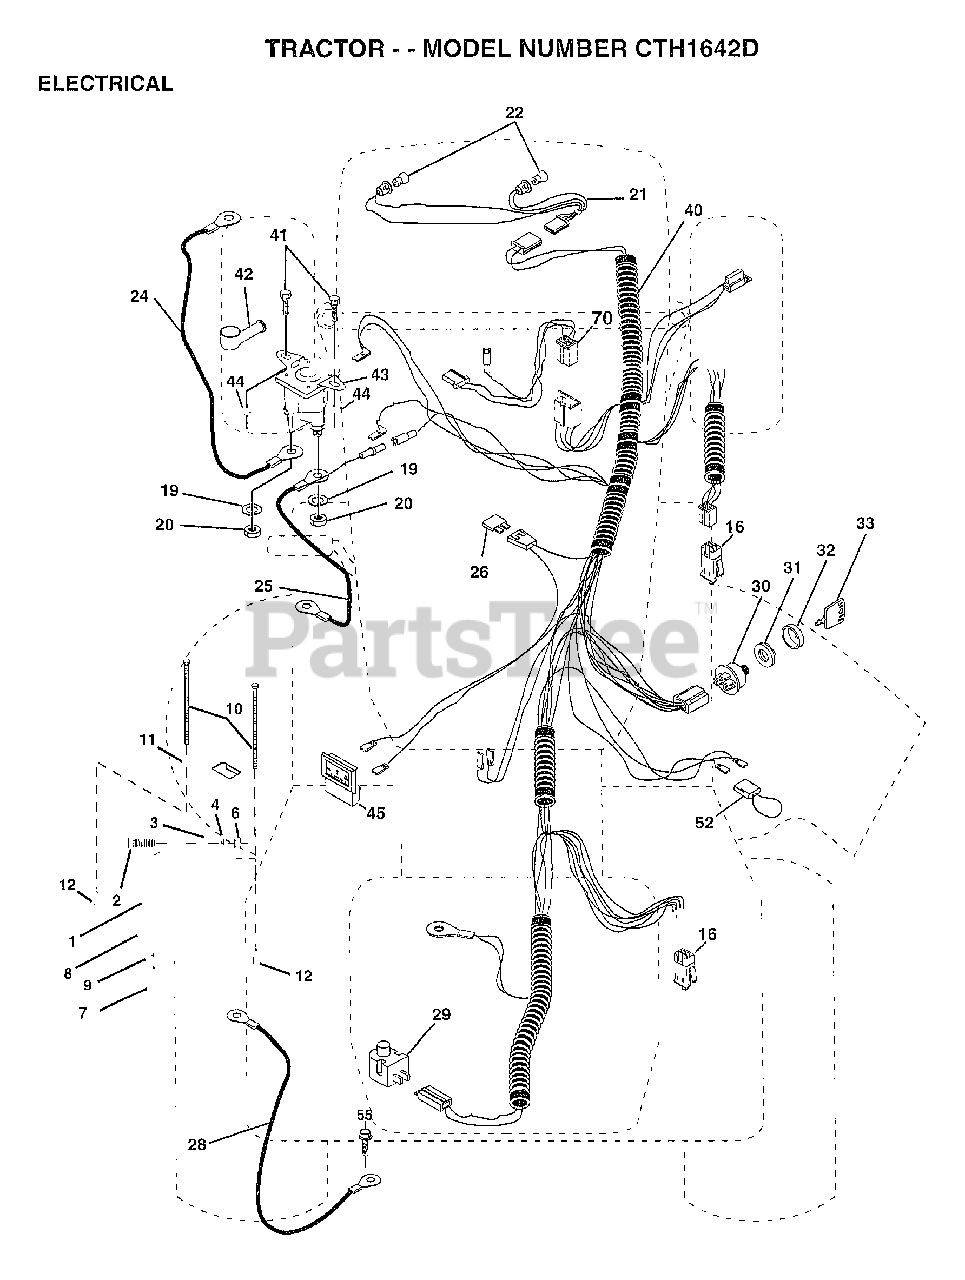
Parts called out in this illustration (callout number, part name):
2	BOLT LT
3	WASHER
4	LOCKWASHER
7	"DRAIN TU T, BATT"
8	"TRAY T, BATTERY"
9	HOSE CLAMP T
11	HOLDDOWN BATTERY
16	SWITCH INTERLOCK
20	NUT
21	"HARNESS,LIGHT SOC"
22	HEADLAMP BULB
24	"CABLE T, BATTERY"
25	CABLE.6GA.22W/16W
26	FUSE HYT
28	CABLE.GRND.6GA.21
29	SWITCH SEAT
30	SWITCH IGN 4POS
31	NUT IGNITION
32	COVER KEY SWITCH
33	KEY
40	"HARNESS-IGN,YDPRO"
41	BOLT HXHD FIN
44	NUT HXKEP 1/4X20
52	PROTECTION LOOP
55	SCREW LT
70	HARNESS ENG DUAL
